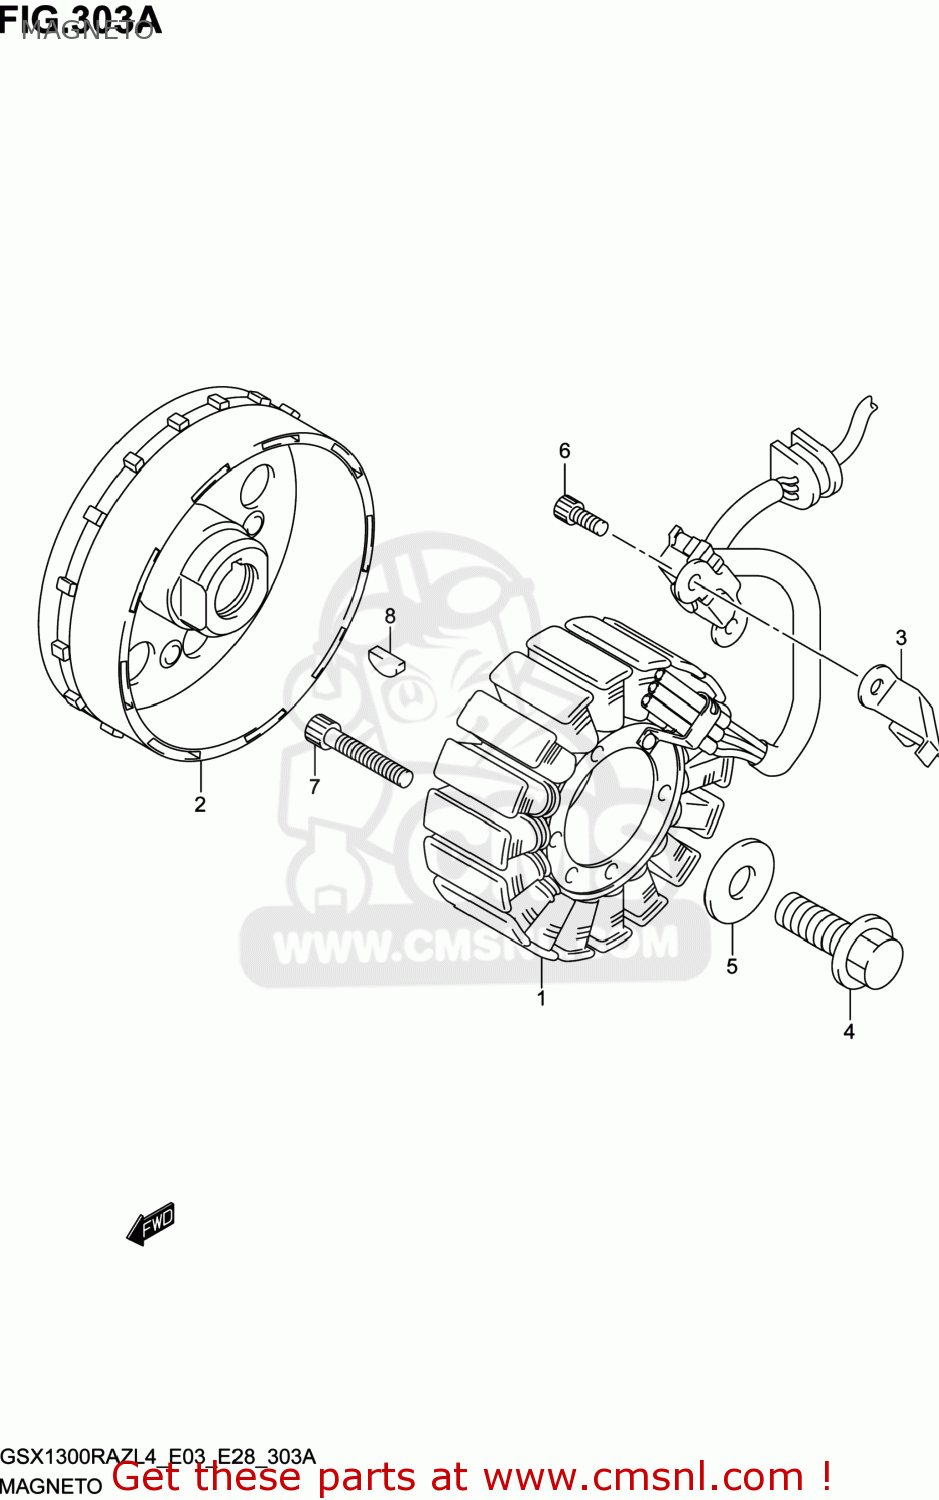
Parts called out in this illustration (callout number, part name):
1	STARTER ASSY
2	ROTOR ASSY
3	CLAMP,MAGNETO LEAD
4	BOLT(12X30)
5	WASHER(12X30X3)
6	BOLT
7	BOLT
8	KEY
